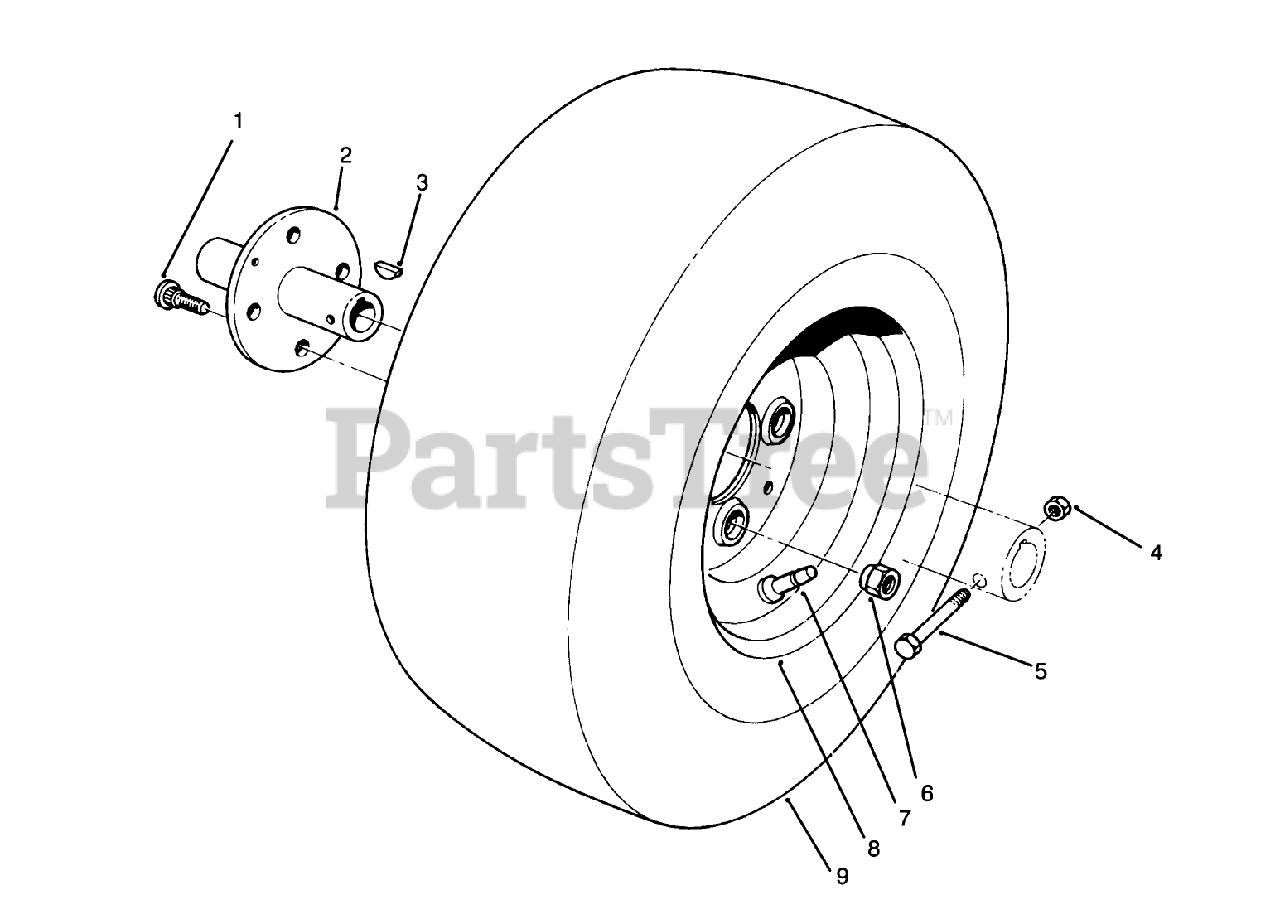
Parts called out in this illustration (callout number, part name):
1	1/2-20X1.25 BOLT
2	WHEEL HUB
3	KEY-WOODRUFF
4	NUT-LOCK, NI
5	SCREW-HH
6	NUT-LUG
7	STEM-VALVE
9	TIRE-4-Ply
